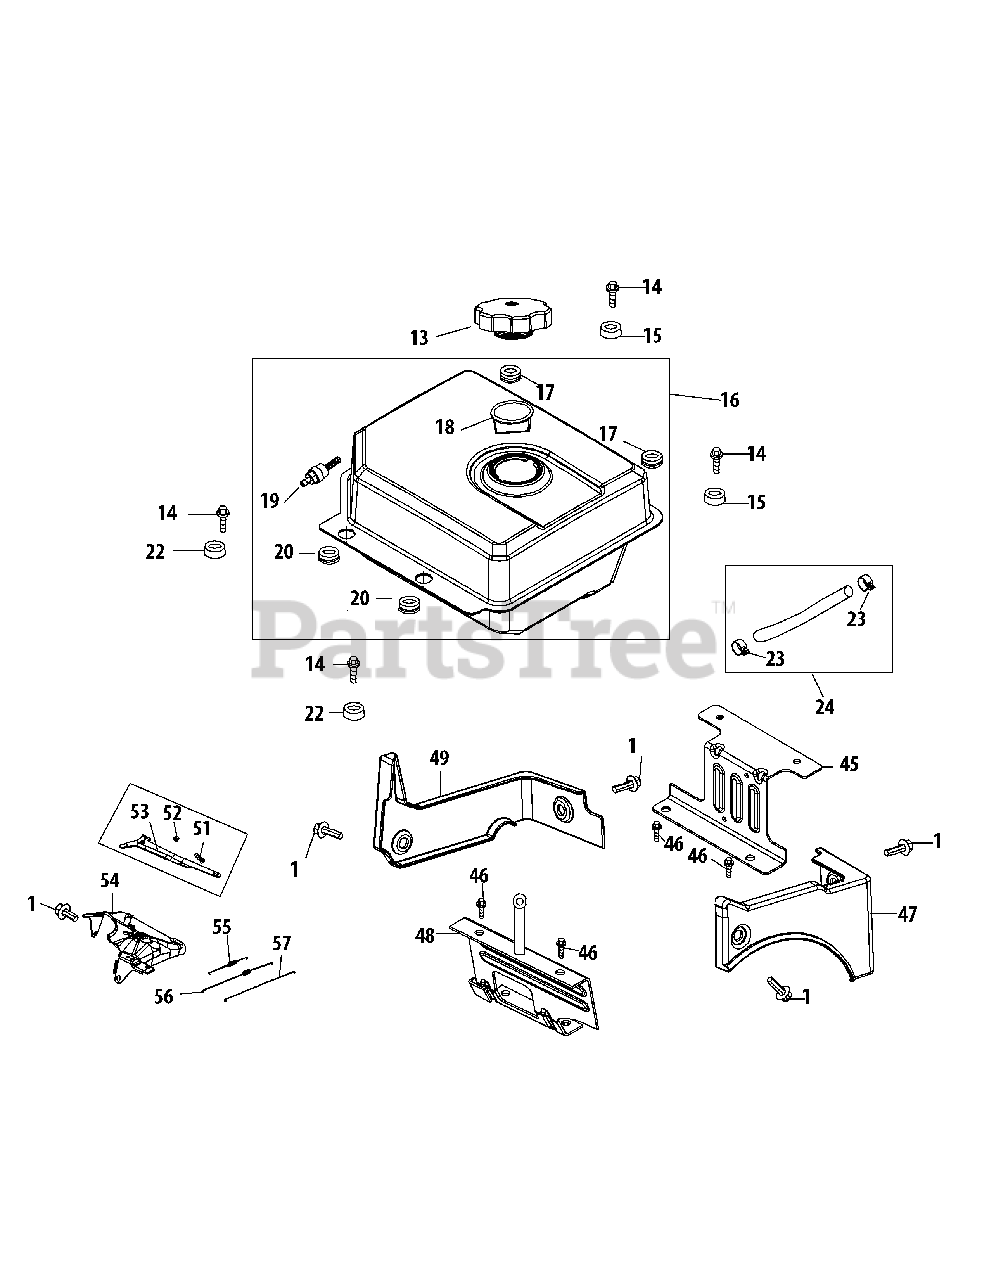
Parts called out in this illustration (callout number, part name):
1	BOLT M6×12
13	FUEL CAP ASSEMBLY
14	BOLT M8×20
15	BUSH?,GAS TANK
16	FUEL TANK ASSEMBLY
17	VIBRATION PAD
18	FUEL LEVEL INDICATOR
19	DRAIN PIPE
20	VIBRATION PAD
22	BUSH ?,GAS TANK
23	FUEL HOSE CLAMP
45	REAR MAINTING BRACKET ASSY.
46	BOLT M8×14
47	RIGHT TRIM PLATE
48	GAS TANK SUPPORT BRACKET
49	LEFT TRIM PLATE
51	GOVERNOR ARM BOLT
53	GOVERNOR ARM
54	THROTTLE BRACKET
55	GOVERNOR SPRING
56	THROTTLE LINKAGE SPRING
57	THROTTLE LINKAGE
